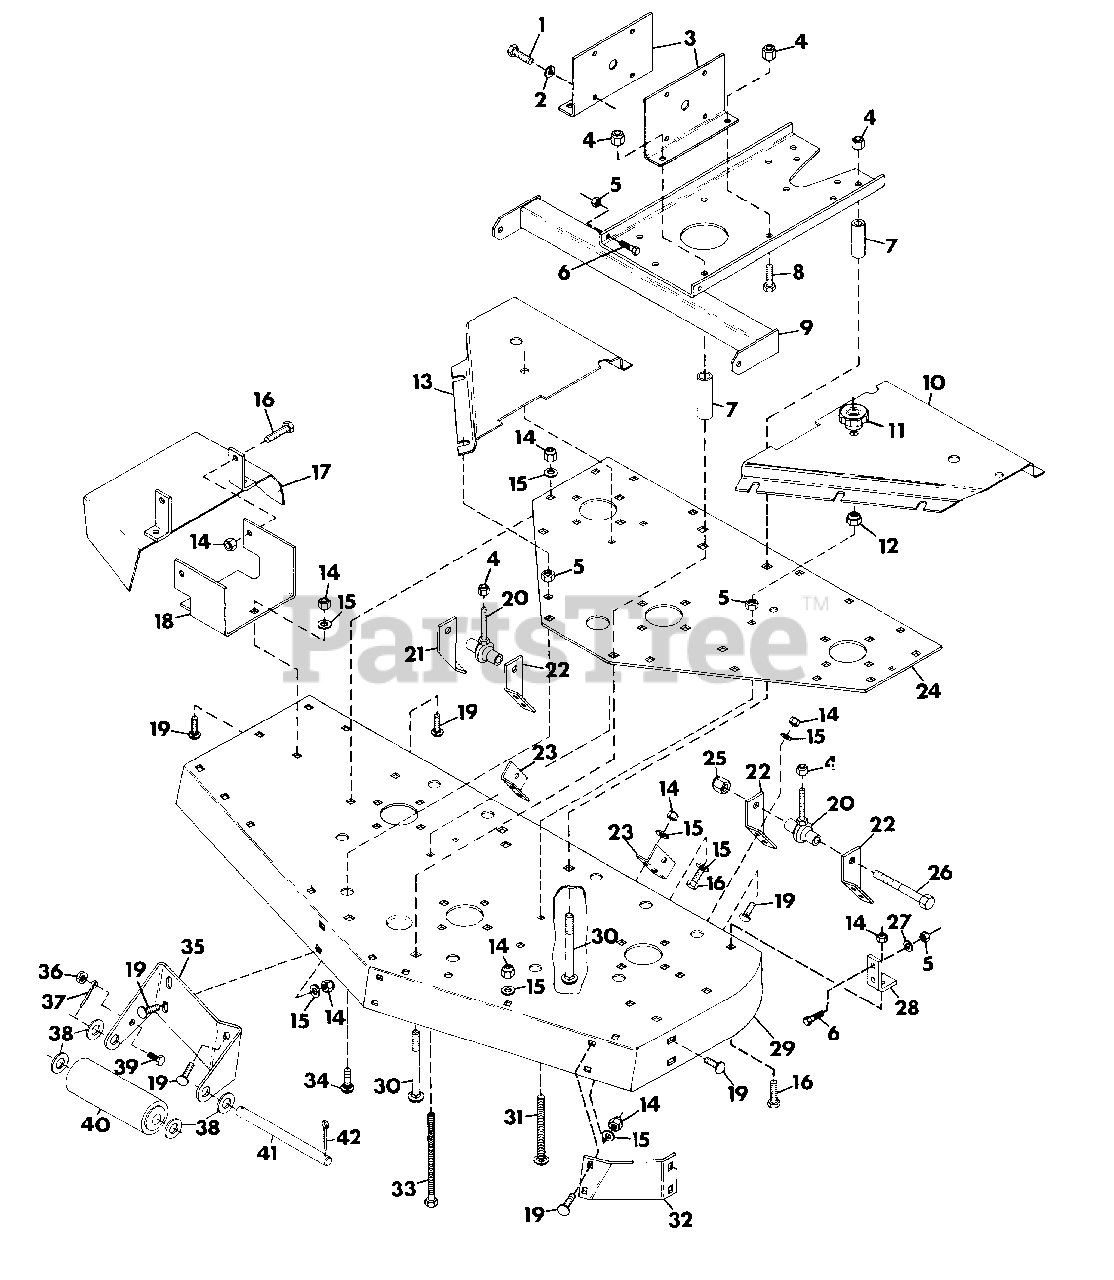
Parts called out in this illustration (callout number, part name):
1	BOLT, HEX 3/8-16X.875
2	WASHER, LOCK 3/8 REG.
3	PLATE, GEARBOX SUPPORT
4	NUT, LOCK 1/2-13
5	NUT, JAM 5/16-18
6	BOLT, HEX 5/16-18X1.25
7	SPACER, .850X.546X2.18
8	BOLT, HEX 1/2-13X1.25
9	WELDMENT, SUPPORT PLATE
10	COVER, BELT L.H.
11	KNOB
12	NUT, LOCK 5/16-18
13	COVER, BELT R.H.
14	NUT, LOCK 3/8-16
15	WASHER, FLAT .406X.812X.065
16	BOLT, HEX 3/8-16X1.00
17	WELDMENT, DISCHARGE CHUTE
18	BRACKET, DISCHARGE
19	BOLT, 3/8-16X1.00 RD HD SQ NK
20	ROD, END
21	PLATE, REAR ADJUSTMENT
22	PLATE, REAR ADJUSTMENT
23	BRACKET, LIFT
24	PLATE, SUPPORT
25	NUT, LOCK 3/4-10
26	BOLT, HEX 3/4-10X3.50
27	WASHER, FLAT .344X.688X.065
28	BRACKET, LIFT PIVOT
29	WELDMENT, 60" MOWER
30	BOLT, 1/2-13X3.75 RD HD SQ NK
31	BOLT, 5/16-18X4 RD HD SQ NK
32	BAFFLE, FRONT
33	BOLT, HEX 5/16-18X3.50
34	BOLT, CARRIAGE 5/16-18X1.0
35	BRACKET, ROLLER FRONT
36	NUT, HEX 1/4-20
37	PIN, COTTER .25X2.0
38	WASHER, FLAT .656X1.312X.095
39	BOLT, HEX 1/4-20X.75
40	ROLLER, GAUGE
41	SHAFT, CENTER ROLLER
42	PIN, COTTER .25X1.0
NS	DECAL, DANGER HAND
NS	DECAL, DANGER FOOT
NS	DECAL, WARNING EYE
NS	DECALS, PRO MASTER-60 MOWER
NS	STRIPE
NS	DECAL, LUBE
NS	DECAL, BELT DIAGRAM
